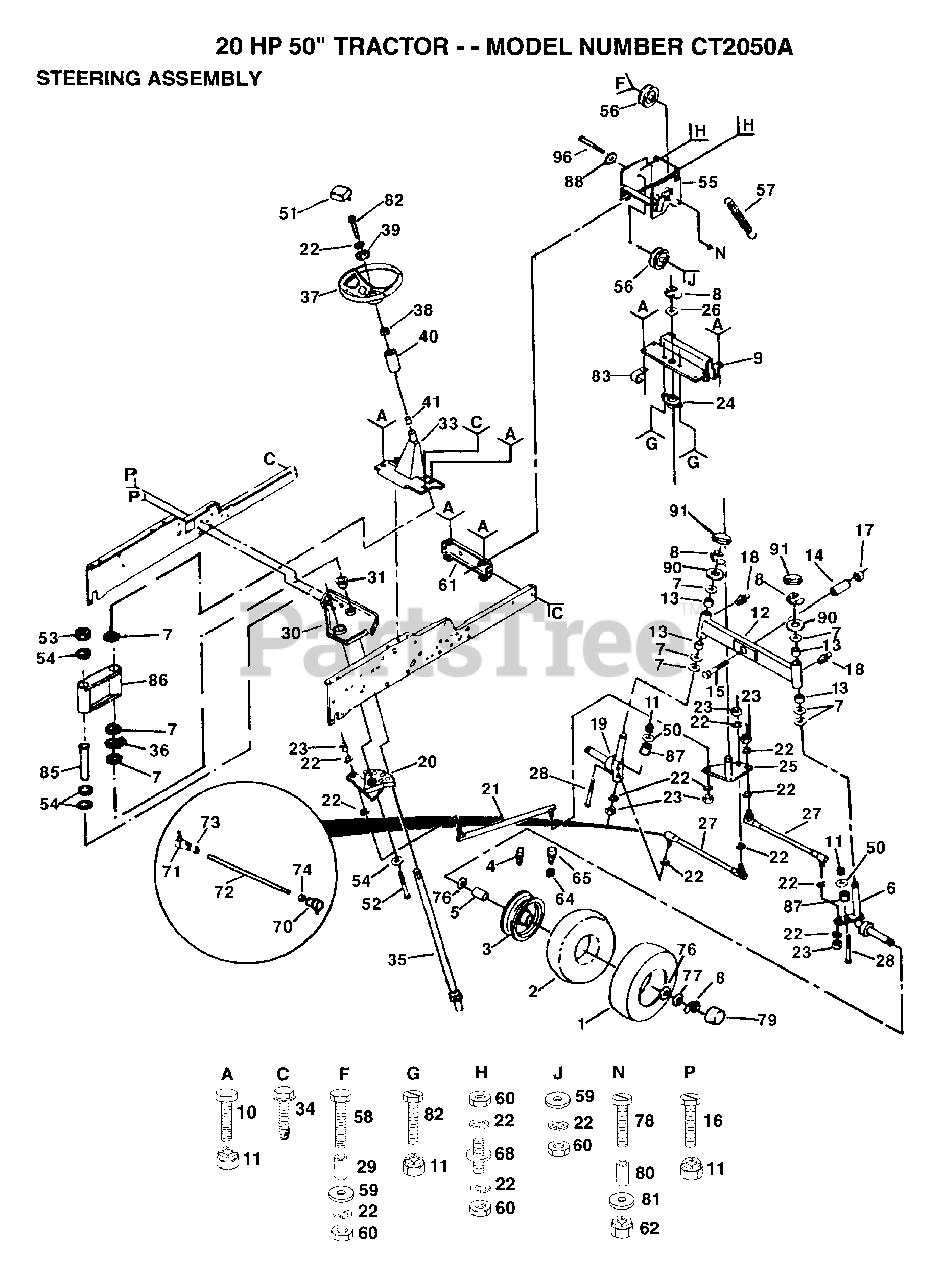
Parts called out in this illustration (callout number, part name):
2	TUBE.16X6.5/7.5-8
4	FITTING LT
5	"FLANGE, BEARING"
6	SPINDLE RH T
7	WASHER .T
8	RING
9	AXLE BRACKET T
12	AXLE ASSEMBLY
13	BRNG. T
15	BOLT
16	BOLT
17	SPACER BEARING
17	LOCKNUT M
18	ZERK M
19	SPINDLE ASSY T
20	SECTOR T
21	LINK.DRAG.T
22	LOCKWASHER
25	"T, BELLCRANK"
26	WASHER
27	TIE ROD T
28	BOLT
29	SPLIT SPACER YTV
31	"FLANGE GT, BEAR."
33	SUPPORT ASSY T
34	SCREW
35	SHAFT ASSY GT
36	KLIP RING
38	ADAPTER LT
39	WASHER T
40	SLEEVE LTV
41	"T, BEARING"
50	WASHER T
51	ST WHL INSERT CAP
52	BOLT T
53	NUT LTV
54	WASHER GT
55	IDLER BRKT T
56	IDLER-INSIDE T
57	SPRING
58	BOLT
59	WASHER
60	NUT.HEX.3/8-16UNC
61	FRAME BRACKET GT
64	VALVE STEM LT
65	VALVE CAP
70	JOINT.RH
71	JOINT.LH
73	NUT
74	NUT
76	WASHER
77	WASHER
79	HUB CAP
80	BUSHING LT
81	WASHER
82	BOLT
83	CLIP GTV
85	TUBE T
86	COLLAR
87	SPACER LT
88	WASHER T
90	WASHER
91	CAP
